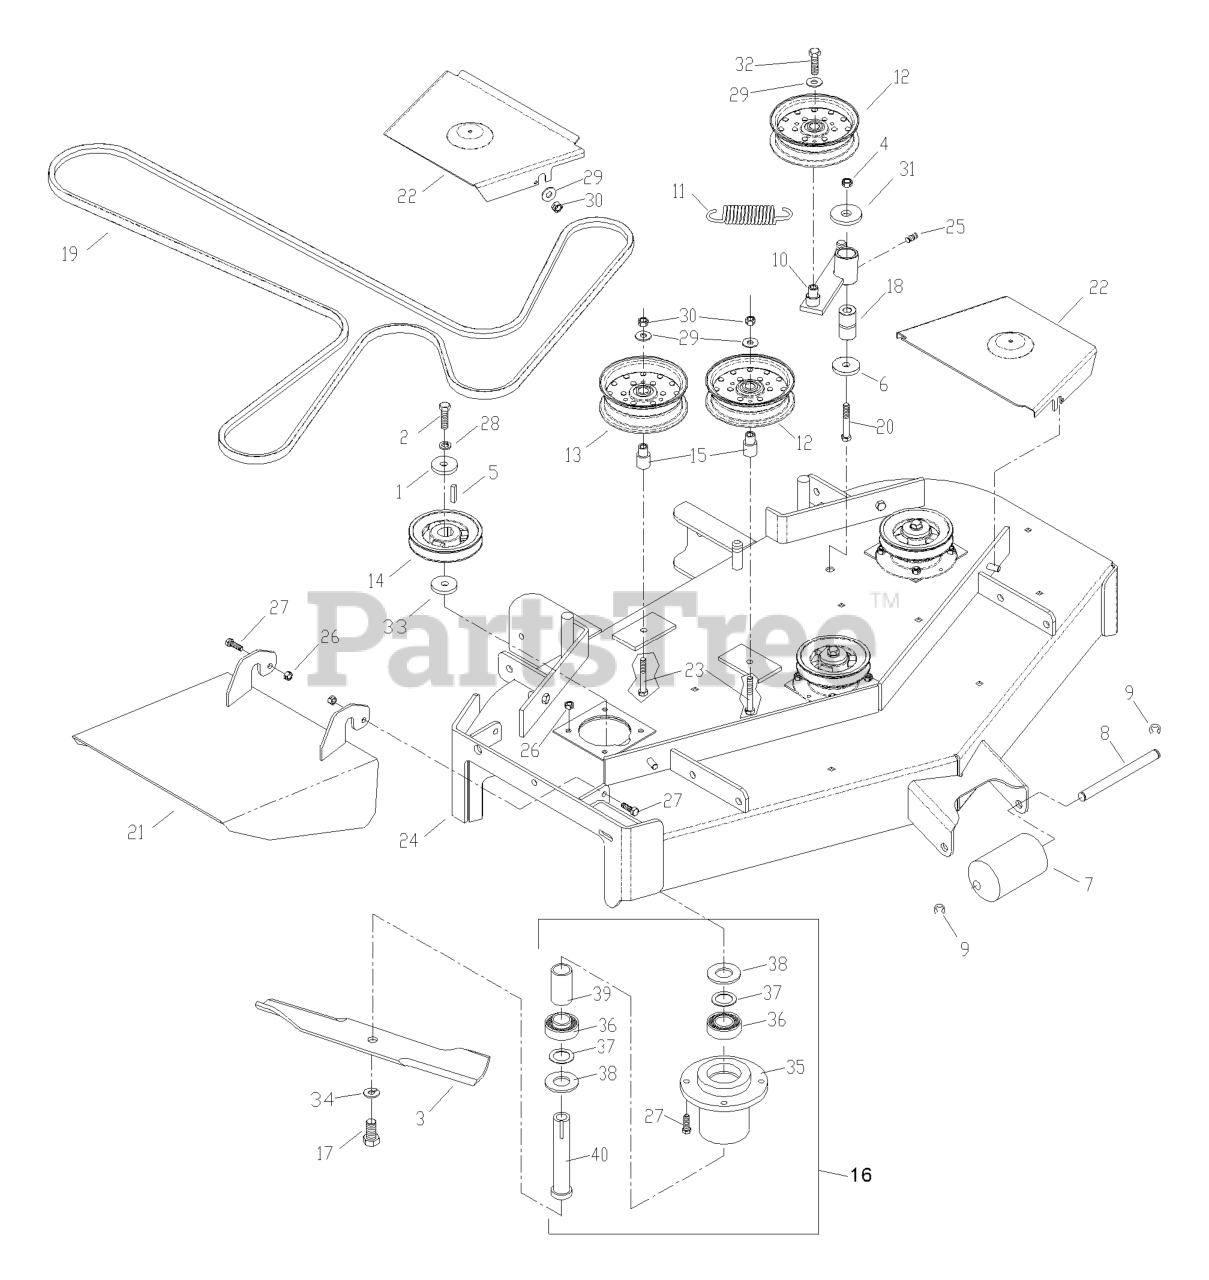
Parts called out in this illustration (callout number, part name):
1	SPINDLE WASHER
2	HCS 7/16F X 1 1/2
3	BLADE OEM, 14-7/8
4	NUT 1/2-13 HEX NYLOC ZD
5	KEY 1/4 SQ X 1 1/8
6	WASHER, SUPPORT
9	E-RING 1/2 (2 2)
12	IDLER PULLEY
13	IDLER PULLEY (TALL)
15	IDLER BUSHING
16	HOUSING ASM.
17	HCS 5/8F X 1 1/4
18	PIVOT BUSHING
19	BELT
20	HCS 1/2C X 3 1/4
21	DISCHARGE CHUTE 42"
22	BELT SHIELD
23	HCS 3/8C X 2 1/2
24	DECK W/DECALS
25	ZERK
26	NUT 5/16C CENTERLOCK
27	HCS 5/16C X 1
28	WASHER 7/16 LOCK
29	WASHER 3/8 FLAT
30	NUT 3/8C CENTERBLOCK
31	WASHER 1/2 FLAT
32	4CS 3/8C X 1 SERRATED HEAD
33	MACHINERY BUSHING 10 GA.
34	LOCKWASHER 5/8
35	HOUSING, DIE CAST
36	BEARING
37	BUSHING.MACHINE.18.GAUGE
38	MACHINERY BUSHING 10 GA.
41	MAIN BAFFLE
42	CARRIAGE BOLT 5/16C X 5/8"
43	CENTER BAFFLE
44	WASHER 5/16 FLAT
45	HCS 5/16C X 3/4
